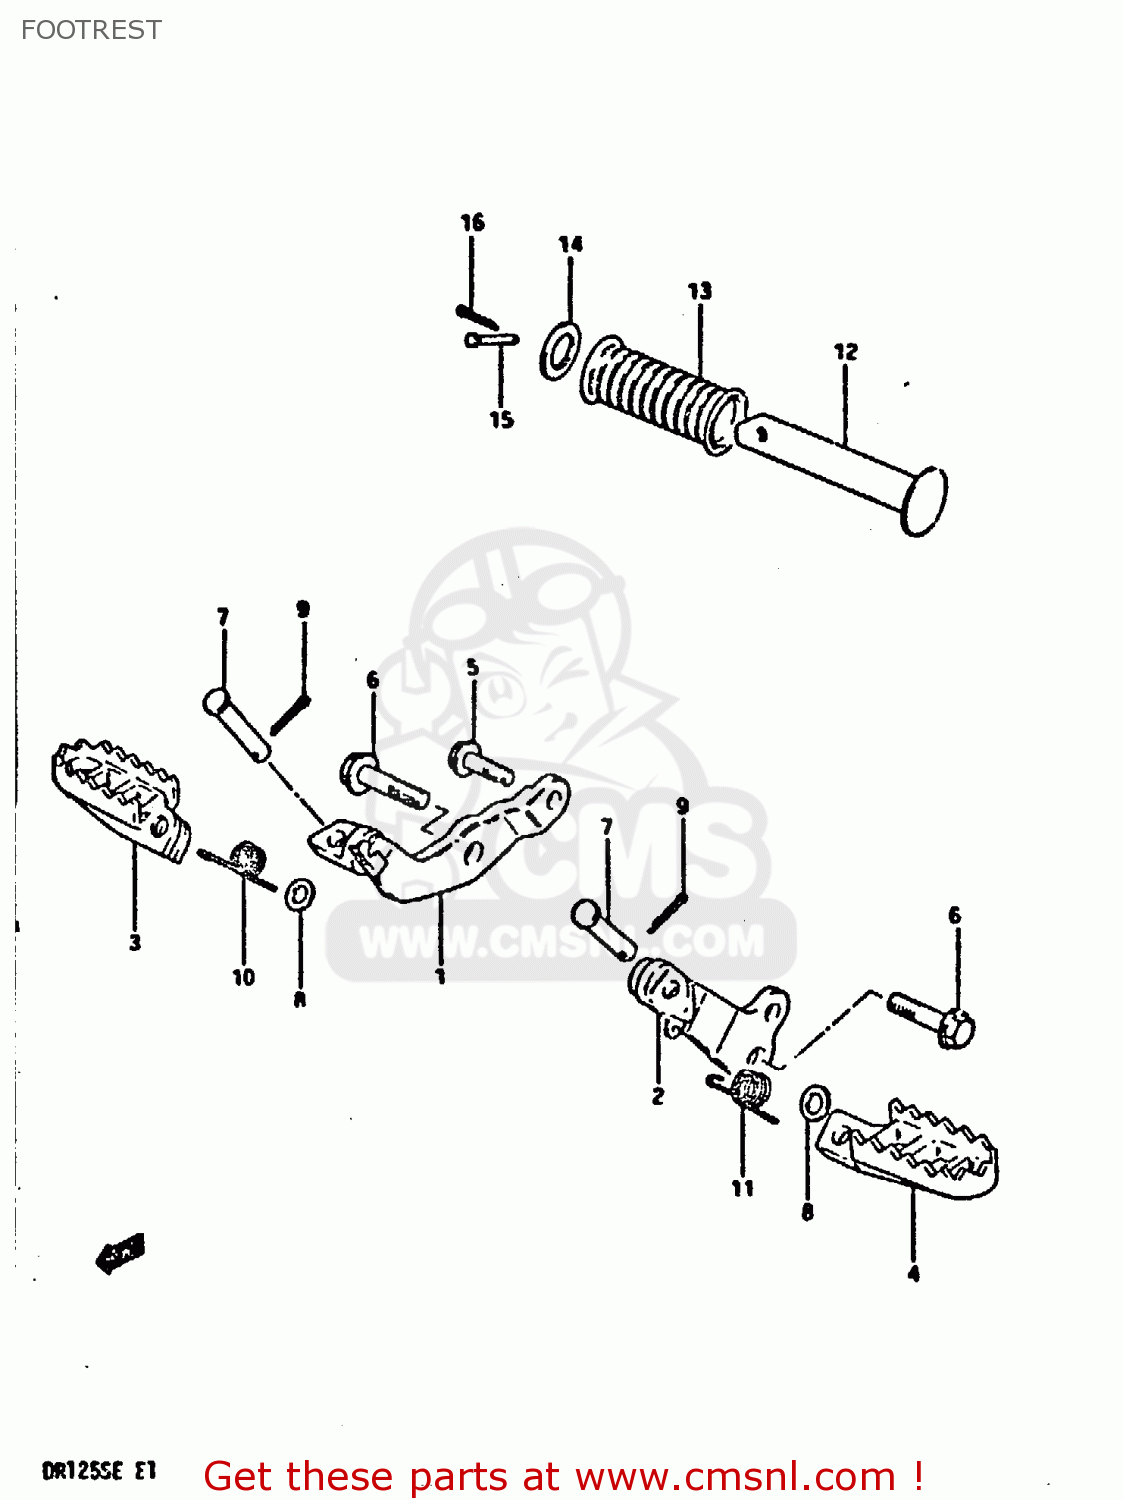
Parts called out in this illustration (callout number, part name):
1	BAR,FRONT FOOTREST
2	BAR,FRONT FOOTREST,LEFT
3	FOOTREST,RIGHT
4	FOOTREST
5	BOLT
6	BOLT
7	PIN
8	WASHER
9	COTTER PIN
10	SPRING
11	SPRING,FOOTREST,LEFT
12	BAR,FOOTREST RUBBER
13	RUBBER,PILLION FOOTREST
14	WASHER (19.5X32X2)
15	PIN
16	PIN 20X20
